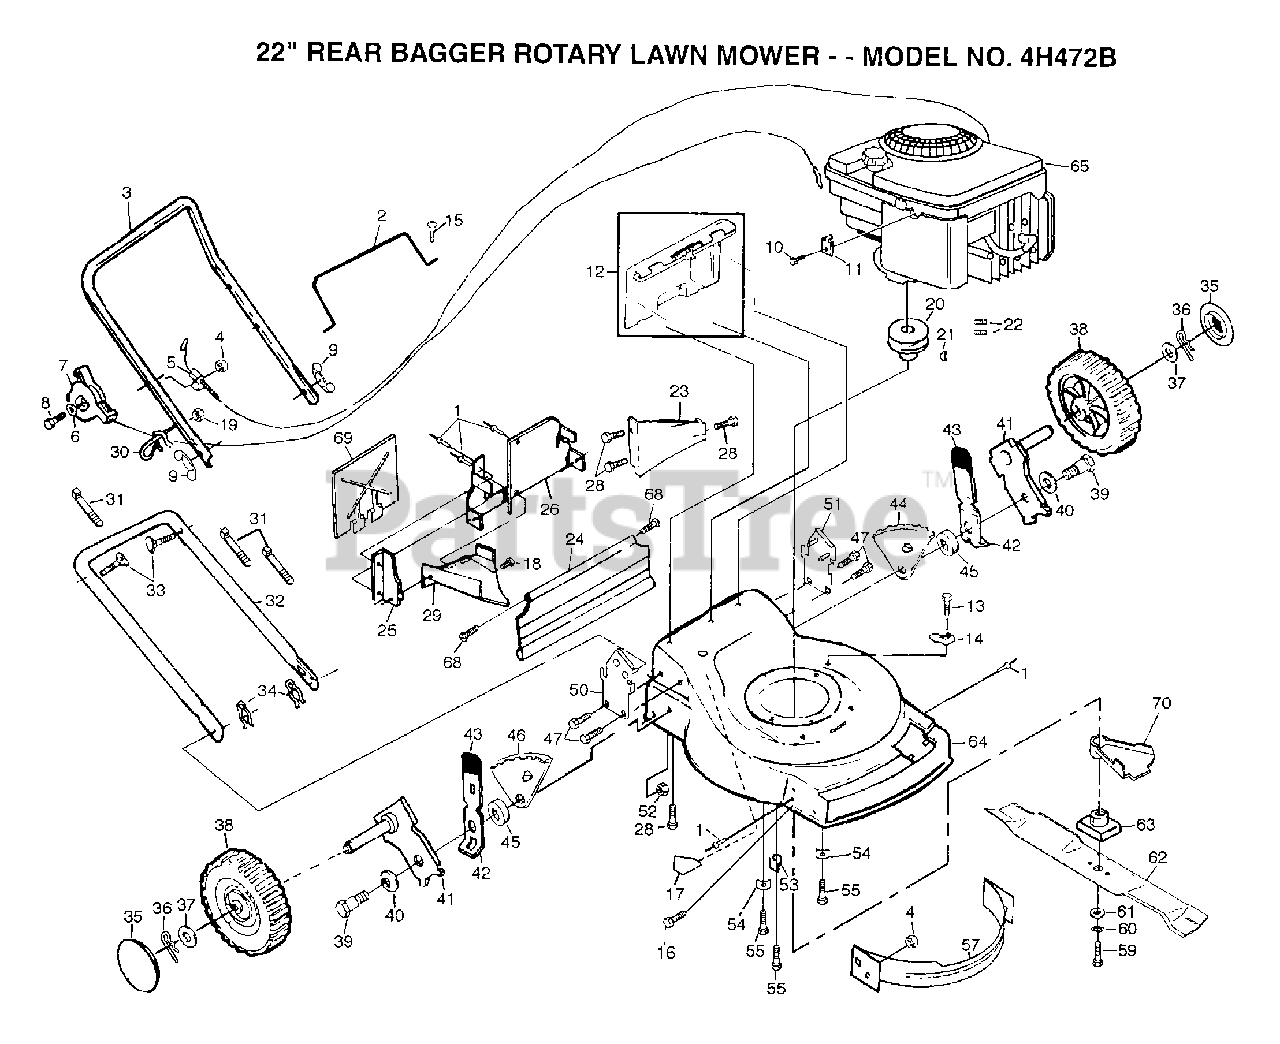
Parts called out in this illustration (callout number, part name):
1	BLIND RIVET
2	CONTROL BAR
5	"CABLE,ENG ZONE CO"
6	WASHER PM
7	"CONTROL, THROTTLE"
9	"NUT,WING PM"
10	SCREW PM
11	CABLE CLAMP
13	TAPPING SCREW
14	GUIDE CLIP PM
15	"SCREW,PAN HD"
16	SCREW
17	DECAL HYT
18	SCREW PM
19	NUT
20	ENGINE.PULLEY.FWG
21	HI PRO KEY PM
22	SCREW
23	REAR BAFFLE
26	PLATE.BACK.22RD
28	SCREW
29	DISCHARGE BAFFLE
30	ROPE GUIDE
33	BOLT.HANDLE.LM
34	HAIRPIN COTTER
35	HUB CAP
36	RETAINER CLIP PM
37	WASHER
40	"WASHER, BELLEVIL."
41	AXLE ARM
42	SPRING SELECTOR
43	KNOB PM
44	BRACKET.ADJ.9.LH
46	BRACKET.ADJ.9.RH
47	SCREW
52	LOCKNUT PM
53	DEBRIS SHLD RET
55	SCREW
59	SCREW
60	LOCKWASHER
61	"WASHER,HARDEN"
63	ADAPTOR.BLADE.LM
64	KIT.HSG.22RD.FWGD
68	HINGE SCREW
69	MULCHER PLATE
